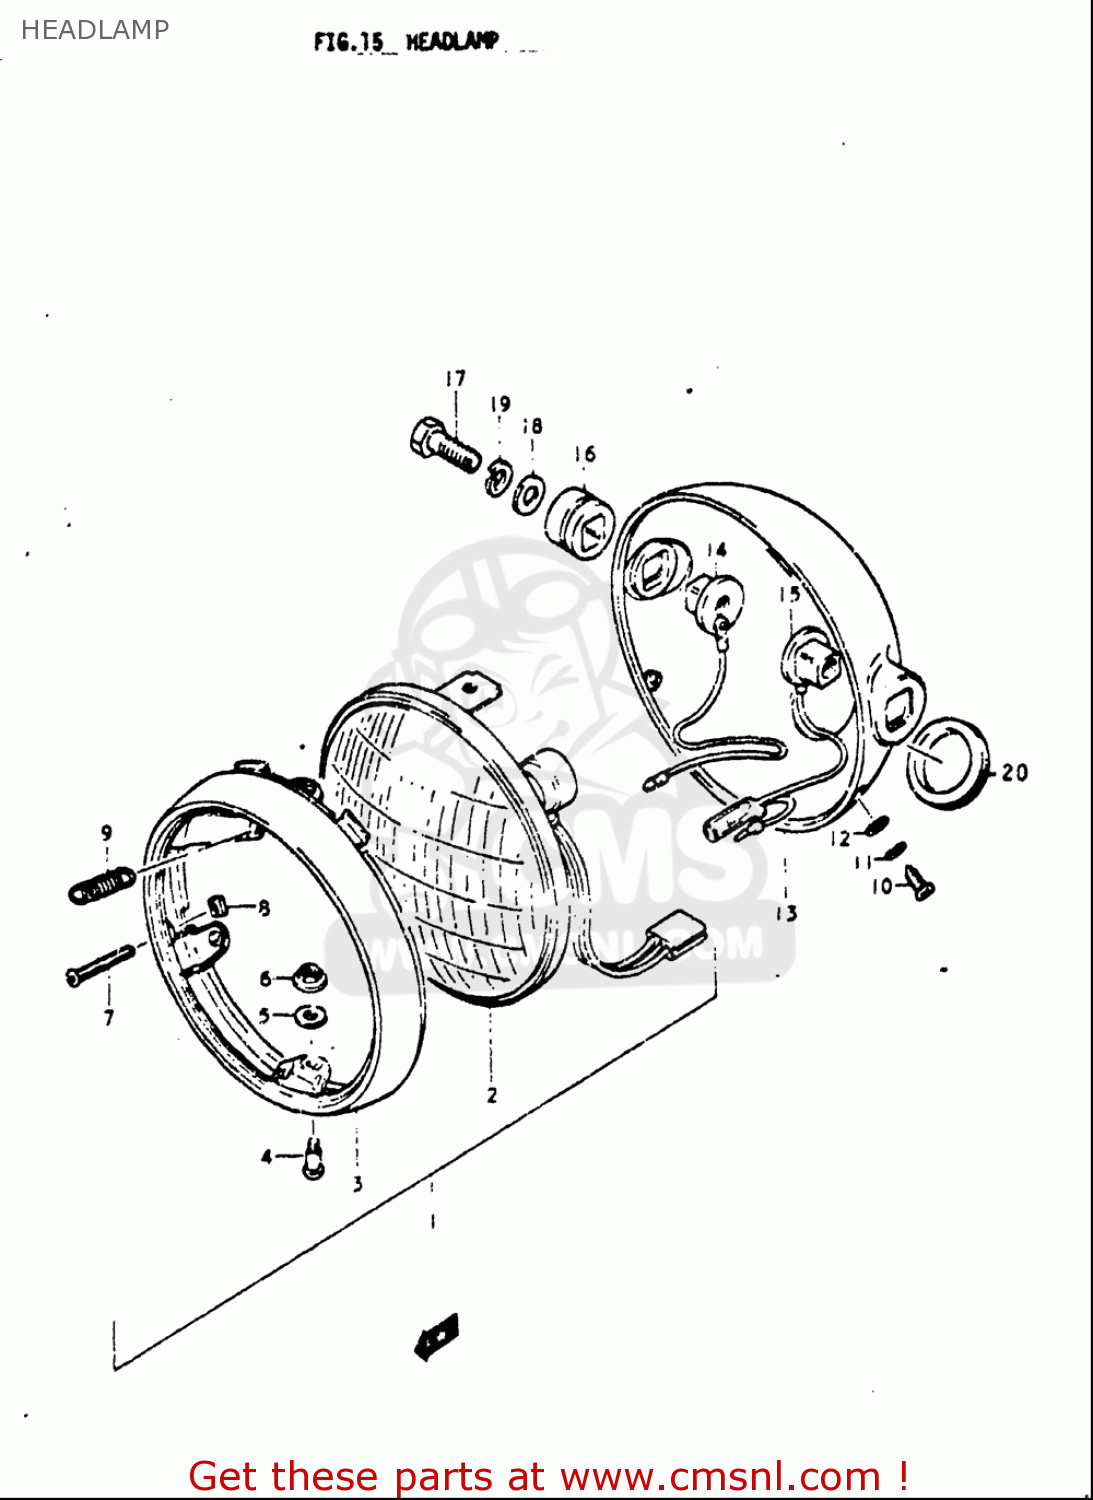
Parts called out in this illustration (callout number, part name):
2	UNIT,HEADLAMP
4	SCREW,HEAD LAMP RIM
6	NUT
7	SCREW,HEADLAMP ADJUST
8	NUT,HEADLAMP ADJUSTER
10	SCREW
11	WASHER,LOCK
12	WASHER
14	SPACER,HEADLAMP HOUSING
16	CUSHION,HEADLAMP HOUSING
17	BOLT
18	WASHER
19	WASHER,LOCK
20	GROMMET,HEADLAMP HOUSING
